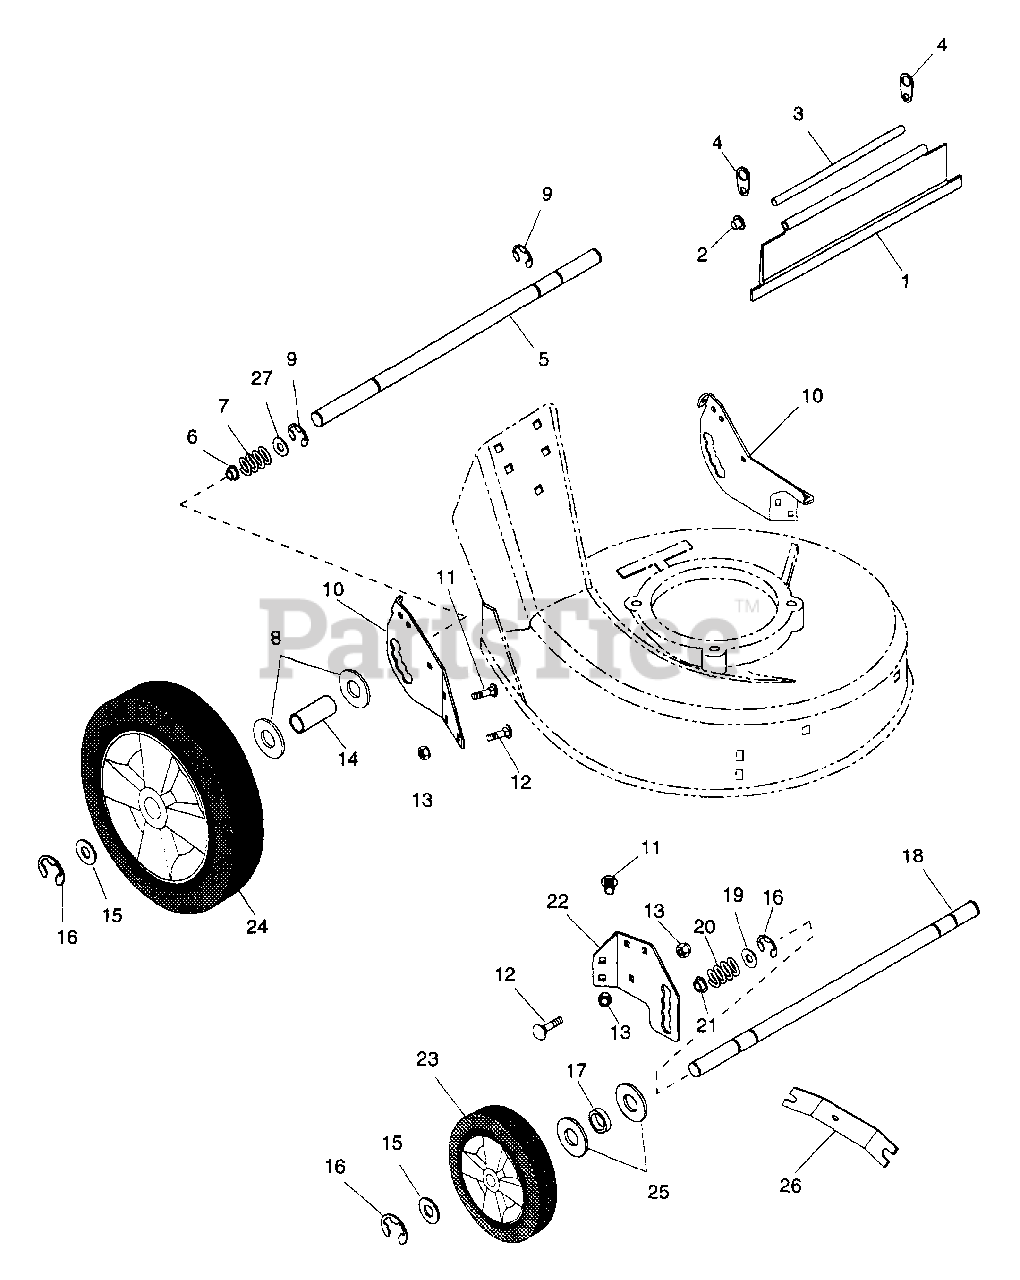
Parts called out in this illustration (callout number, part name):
1	REAR PROTECTIVE GUARD
2	NUT-PUSH .312 DIA. PAL
6	BSHG-FLG .629X.879X.469X1.250
7	SG-COMP .072X.77X1.75
8	WSHR-FL-STL .630X1.005X.062 PL
9	RG-RTNG-EXT .625X.042
10	LH REAR QUADRANT
10	RH REAR QUADRANT
11	BLT-RDHDSQSHNK .31-18X.50 YZ
12	BLT-RDHDSQNK .312-18X.62SHTPL
13	NUT-FLG. .312-18 PL
14	SPACER TUBE, SELF PROPEL
15	WSHR-FL-STL .505X.880X.072 PL
16	RG-RTNG-EXT .500X.042 (E)
17	BSHG, SPCR.500X.750X.321 PM
19	WSHR-FL-STL .505X.875X.024 PL
20	SG-COMP .62X.68X1.75
21	BSHG-FLG.500X.750X.750X1.000BR
22	RH FRONT QUADRANT
22	LH FRONT QUADRANT
23	TIRE 7X1.50
24	RH REAR WHEEL
24	LH REAR WHEEL
25	WSHR-FL-STL .531X1.062X.095 PL
26	AXLE TOOL
27	WSHR-FL-STL .630X1.250X.062 PL
